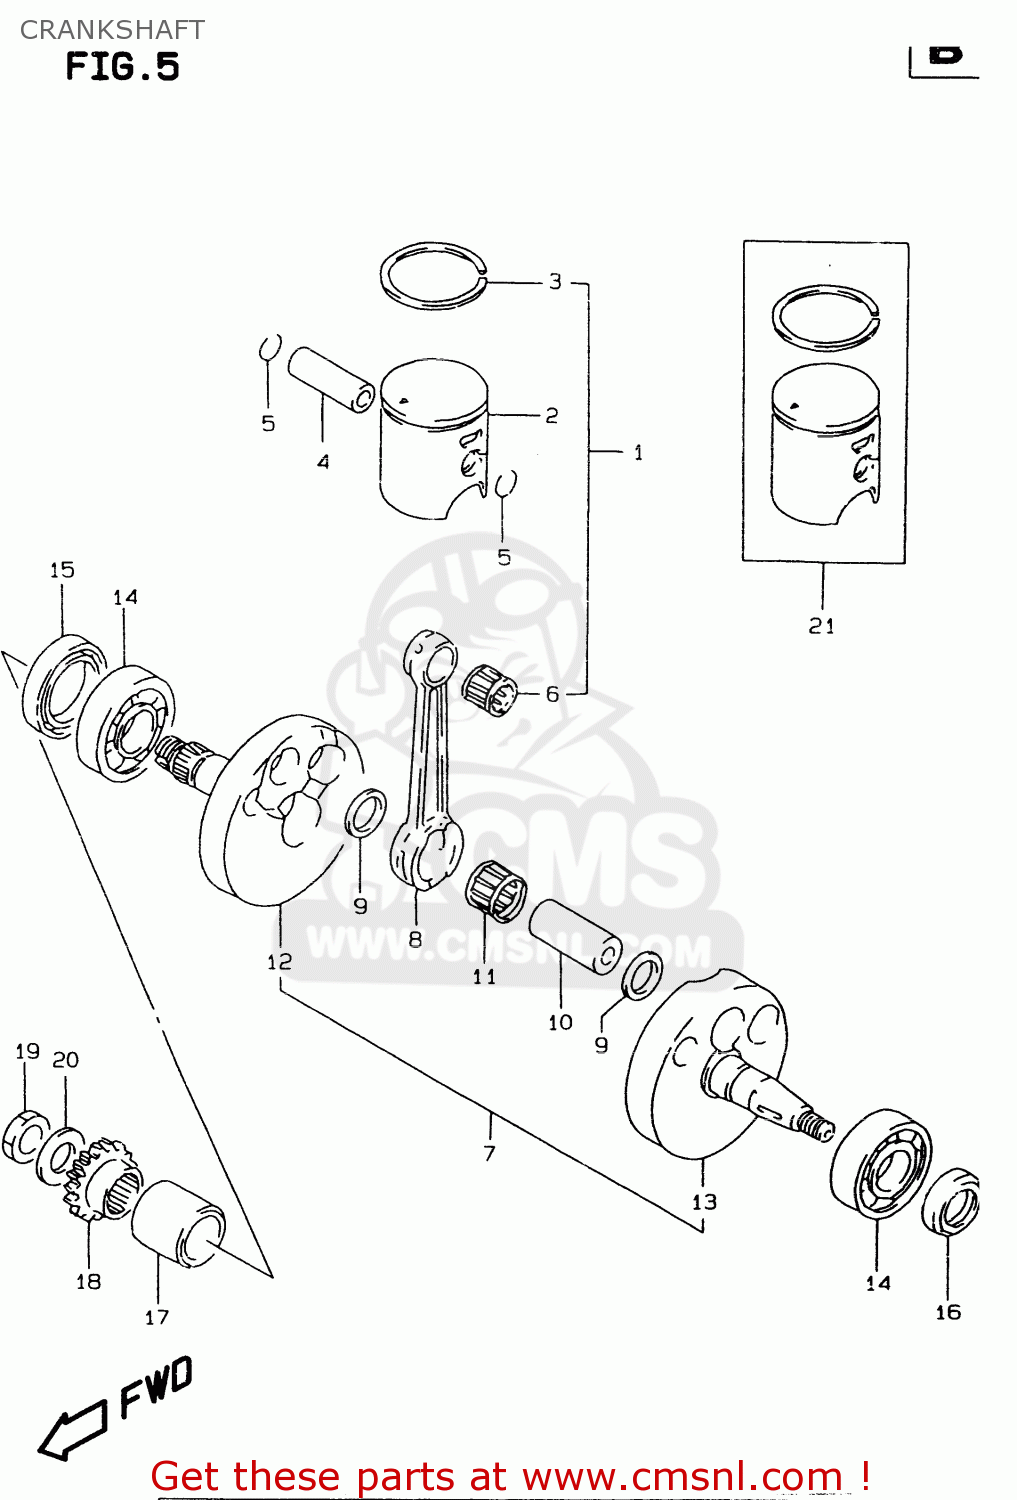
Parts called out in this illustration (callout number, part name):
1	PISTON KIT
2	PISTON
3	RING,PISTON
4	PIN,PISTON
5	RING,SNAP 14MM
6	BEARING(14X18X16)
7	CRANKSHAFT ASSY
8	ROD,CONNECTING
9	WASHER
10	PIN,CRANK
11	BEARING(20X26X13.7)
12	CRANKSHAFT,RIGHT
13	CRANKSHAFT,LEFT
14	BEARING(20X52X15)
15	SEAL,OIL(30X40X7)
16	SEAL,OIL(18X30X6)
17	SPACER,PRIMARY DRIVE GEAR
18	GEAR,PRIMARY DRIVE (NT:
19	NUT
20	WASHER
21	PISTON SET(OS:0.5)
